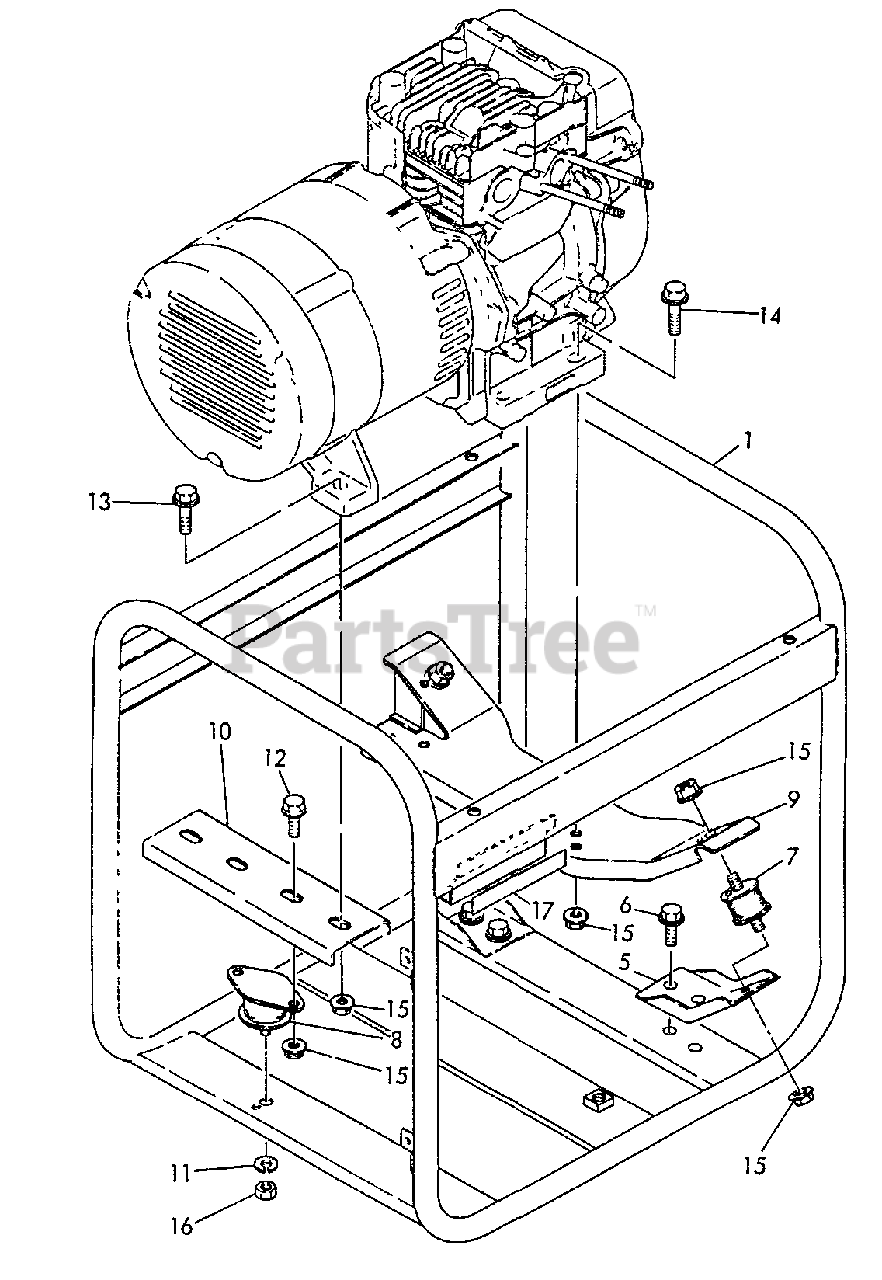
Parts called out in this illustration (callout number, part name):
1	FRAME
5	DAMPER STAY, LOWER
6	BOLT - 8×16 -- PLATED
7	DAMPER, FRONT
8	DAMPER, REAR
9	STAY, DAMPER
10	STAY, REAR DAMPER
11	LOCKWASHER - 10
12	BOLT - 8×20 -- PLATED
13	BOLT - 8×30 -- PLATED
14	BOLT - 8×38 -- PLATED
15	U-NUT M8
16	NUT - 10
17	SHEET, FRAME
